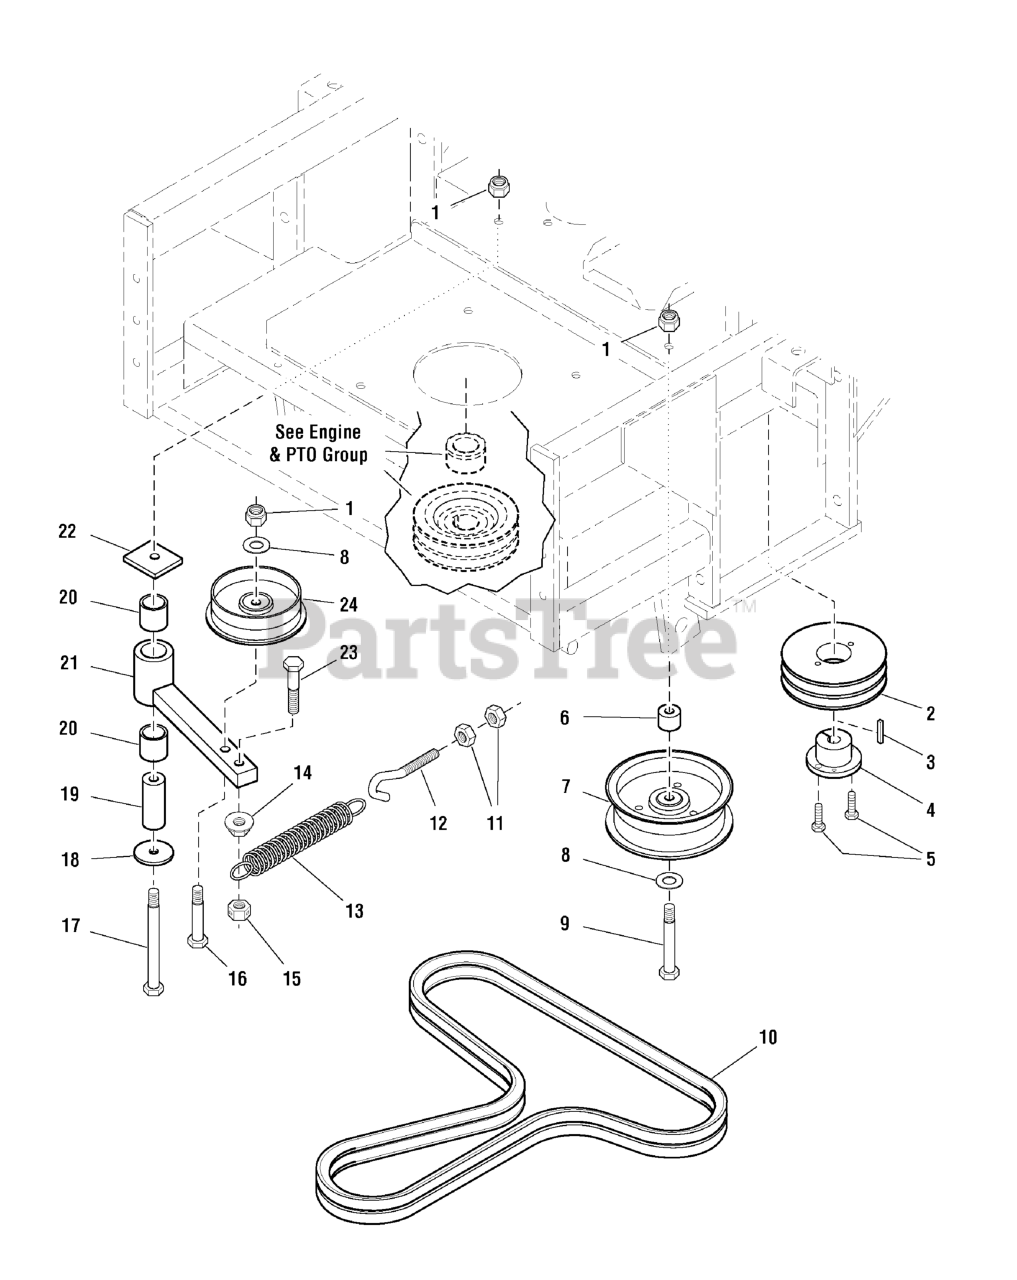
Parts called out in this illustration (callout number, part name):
1	NUT, 3/8-16 HEX NYLON LOCK
2	PULLEY, Pump Drive
3	KEY, 5MM SQ. x 25MM w/ Round Ends
4	BUSHING, Tapered Hub
5	BOLT, 1/4-20 X 1" GD5 CZ
6	SPACER, .39 x 1.00 x .79
7	PULLEY, Idler
8	WASHER, 3/8 SAE
9	BOLT, 3/8-16 X 2-3/4" GD5 CZ
10	BELT, Pump Drive (set of 2)
11	NUT, 3/8-16 Hex
12	SCREW HOOK, 3/8-16 x 4-1/4
13	SPRING, Extension, Swivel End
14	NUT, 3/8-16 Hex Serrated Flange
15	NUT, 3/8-16 Hex Side Lock
16	BOLT, 3/8-16 X 2-1/4" GD5 CZ
17	BOLT, 3/8-16 X 4" GD5 CZ
18	WASHER, 3/8 x 1-3/4
19	SPACER, .39 X 1.00 X 2.55, SS
20	BUSHING, Brass
21	WELD, ARM, PUMP DRIVE IDLER - BLK
22	SPACER, Idler Pivot
23	BOLT, 3/8-16 X 1-3/4" GD5 CZ
24	PULLEY, Idler (Single Flange)
